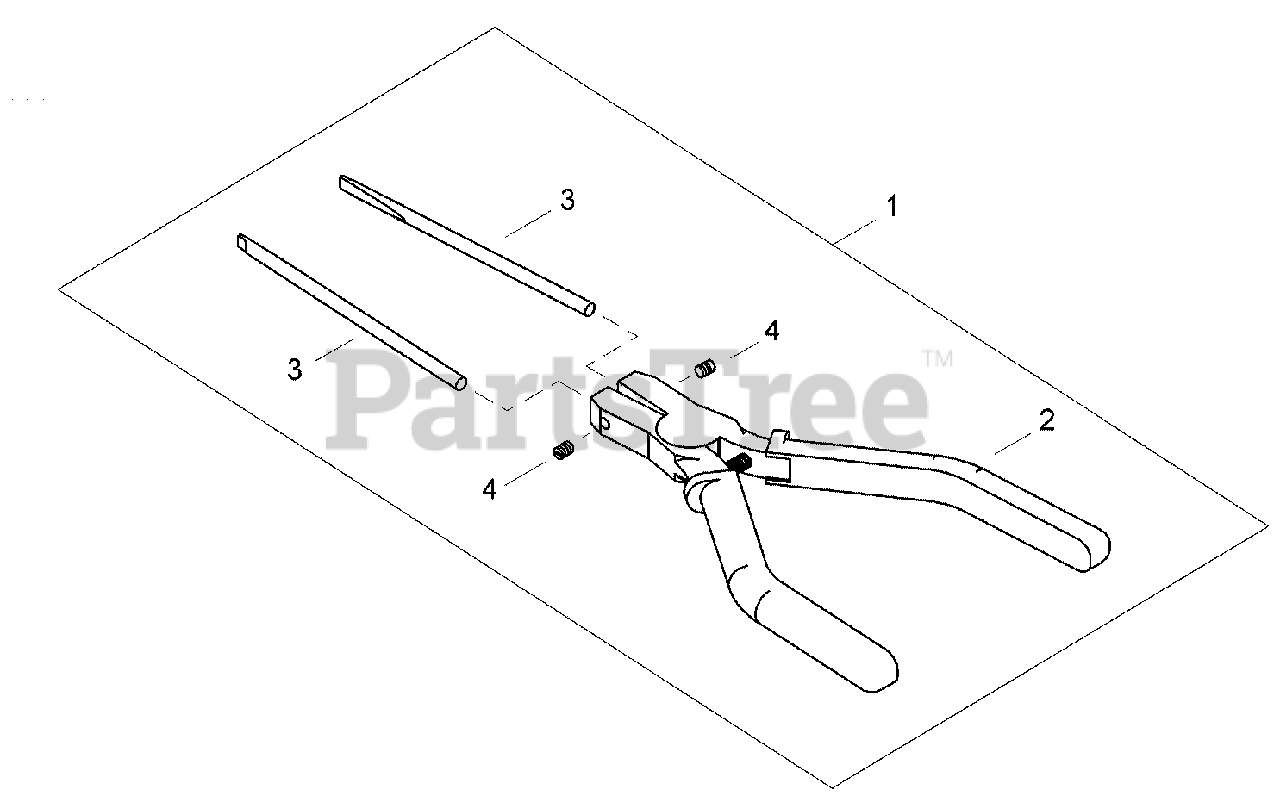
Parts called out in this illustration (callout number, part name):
1	PLIERS
2	PLIERS
4	SCREW - SET
